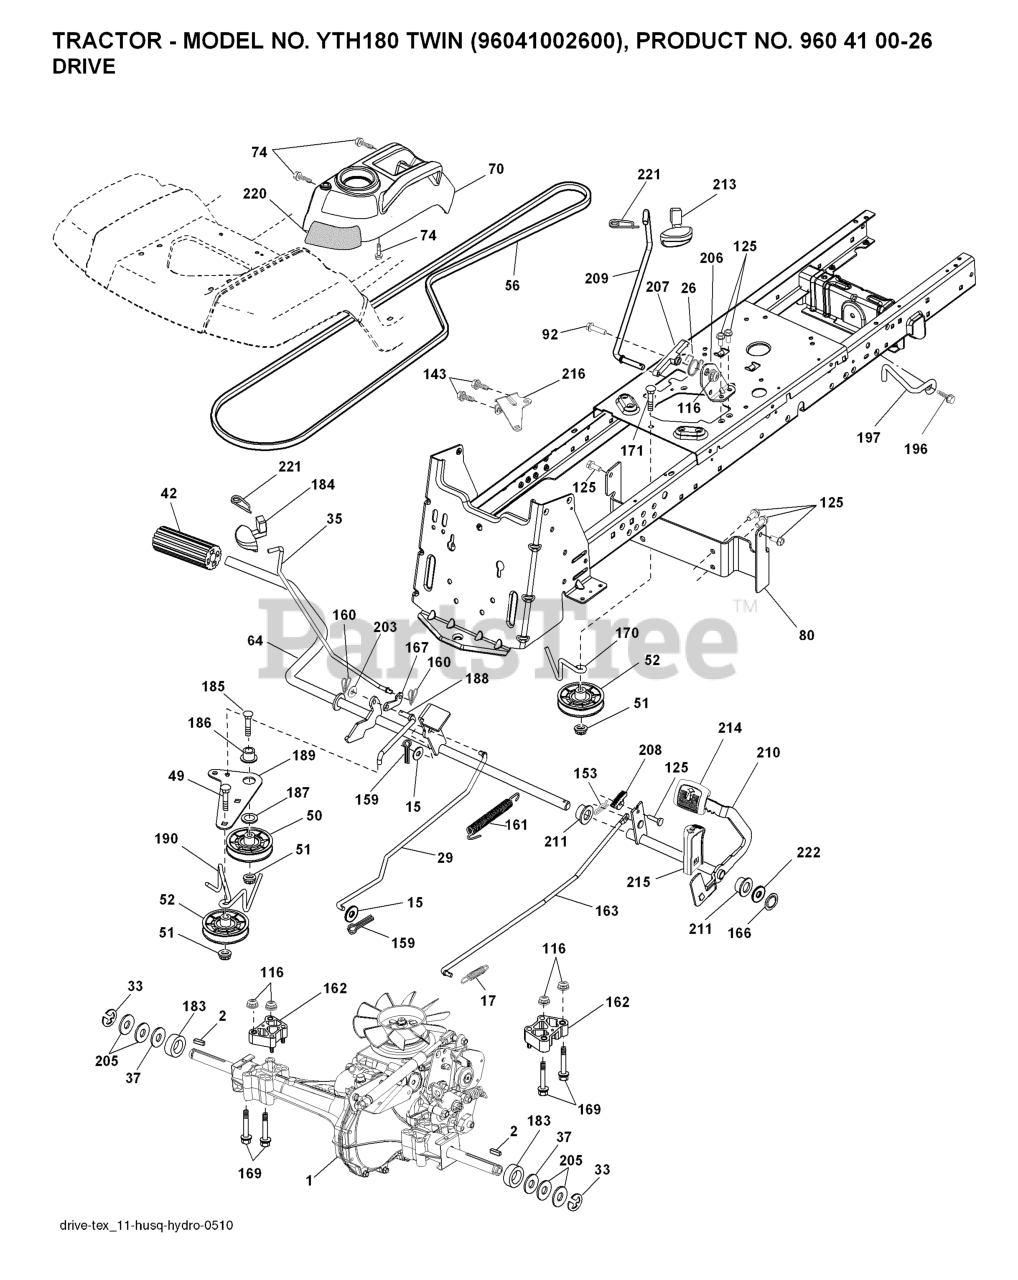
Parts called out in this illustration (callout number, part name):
2	SQUARE KEY
15	WASHER
17	SPRING.BRAKE.HG3000/3500
26	SPRING.RETURN.CRUISE
29	ROD.BRAKE.0610.PEDAL.CONTROL
35	ROD.BRAKE.PARKING.GT.H
42	PEDAL COVER T
50	IDLER.FLAT.910.OFFSET
51	NUT LOCK FLG 3/8-16 UNC
52	IDLER.V-GROOVE.1.688.OFFSET
64	SHAFT.ASM.PEDAL.BRK.CNTR
70	RP CONSOLE.ASM.PCH.W/TB
74	SCREW.HI-LO.CONSOLE
80	BRKT.STRP.TRQ.LT.HYD.C
92	BOLT
116	NUT LOCK HEX FLANGE 5/16-18
125	SCREW
143	Screw 5/16-18 x 1/2 Hex, Self Tapping 5/16-18 x 1/2
153	BATTERY CABLE GT
159	COTTER PIN
160	RETAINER CLIP
161	SPRING.RETURN.CLUTCH.2006
162	SPACER.TRANSAXLE.18&22
163	ROD.PEDAL.CONTROL.0510
166	NUT.PUSH.625.2006
167	LATCH.BRAKE.SPRING
169	BOLT.HEX.FLNG.5/16-18X3.75
170	KEEPER.V-IDLER.CENTER.
183	SPACER AXLE
184	HANDLE.PARKG.BRK.HUSQ X667
186	SPACER.RETAINER
187	WASHER 12/32X2X10GA
188	RP.LINK.CLUTCH.GROUND.DRIVE
189	BELLCRANK.GROUND.DRIVE.TEX.
190	KEEPER.BELLCRANK.DRIVE
196	SCREW 3/8-16X1
197	LINK.CLUTCH.ANIT-ROTAT
203	WASHER
206	BRKT.MOUNT.LATCH.CRUIS
207	LATCH.CONTROL.CRUISE
208	GEAR.SECTOR.CONTROL.CR
209	ROD.CONTROL.CRUISE.GT.
210	ROCKER.ASM.PEDAL.CONTR
211	BEARING.NYLON
213	KNOB.CONTROL.CRUSIE.HU
214	PEDAL.FORWARD.TEX.GT.4
215	PEDAL.REVERSE.TEX.GT.4
216	BRACKET.PULLEY.IDLER.W/TEX
220	REFLECTOR.RH.TEX GT
221	RETAINER.SPRING.CLIP.H
222	WASHER
